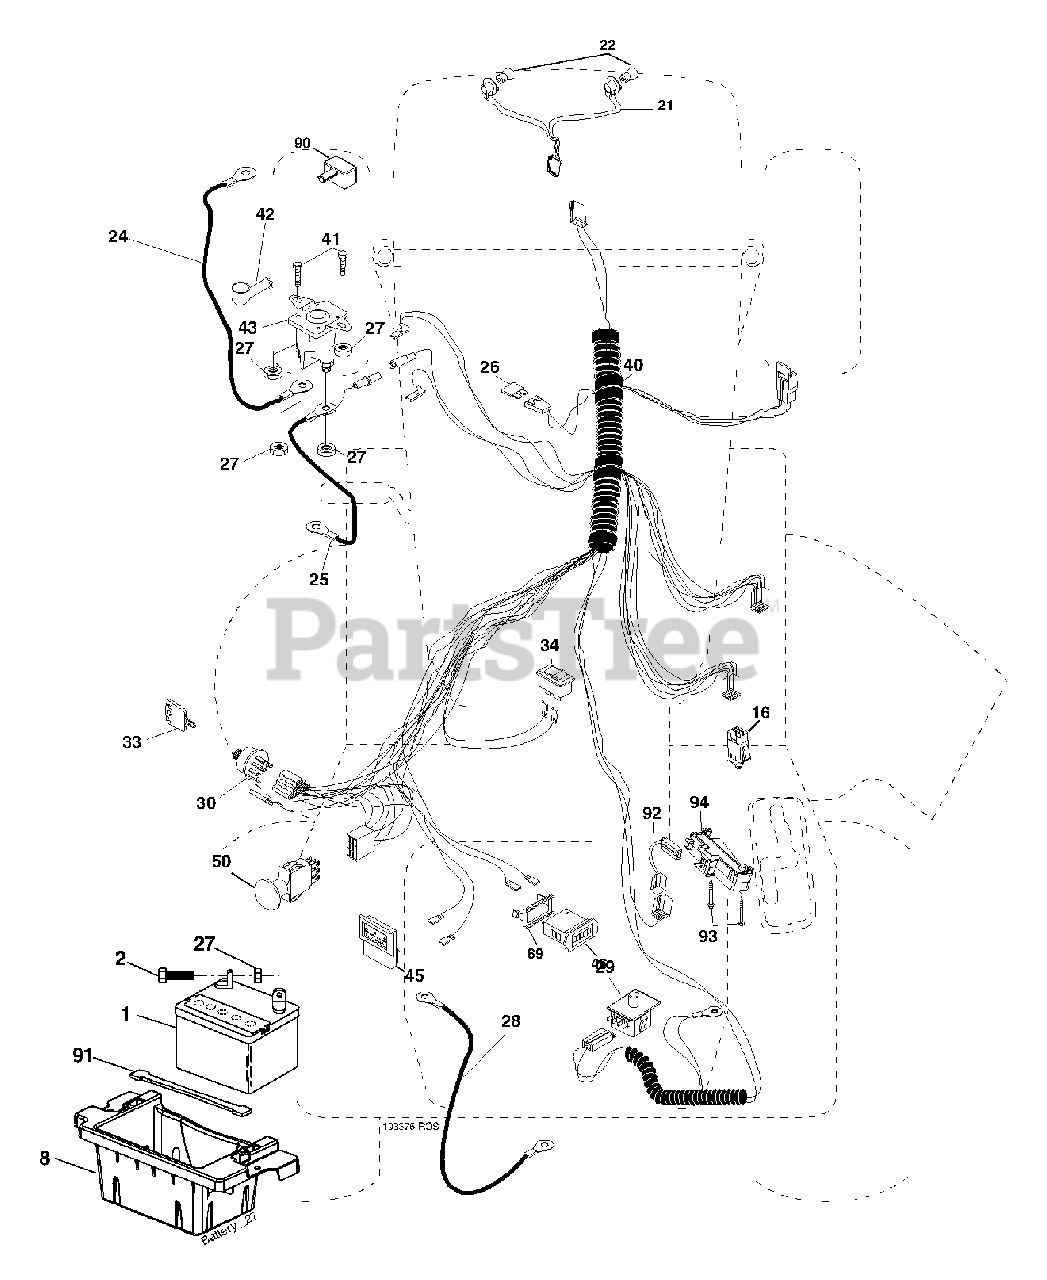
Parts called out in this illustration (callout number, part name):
1	Battery
2	Bolt Hex Hd 1/4-20 unc x 3/4
8	Cable Starter
16	Switch Interlock Push-In
21	Harness Asm Light W/Bulbs
22	Bulb Light
24	Cable Starter
25	Cable Battery
27	Nut Keps Hex 1/4-20 unc
28	Cable Ground
29	Switch Seat
30	Switch Ign
34	Switch Light/Reset
40	Harness Ign.
41	Bolt 1/4-20 x 1/2
42	Cover Terminal
43	Solenoid
45	Ammeter Rectangular
46	Hourmeter Snap-In
50	Switch, PTO
55	Screw Thdrol 5/16-18 x 1/2
89	Bracket Snap-In Hourmeter
90	Cover Terminal Battery
91	Strap Battery
92	Harness Pigtail Reverse Switch
93	Screw Plastite 10-1/4 x 2.0
94	Module Reverse Switch
